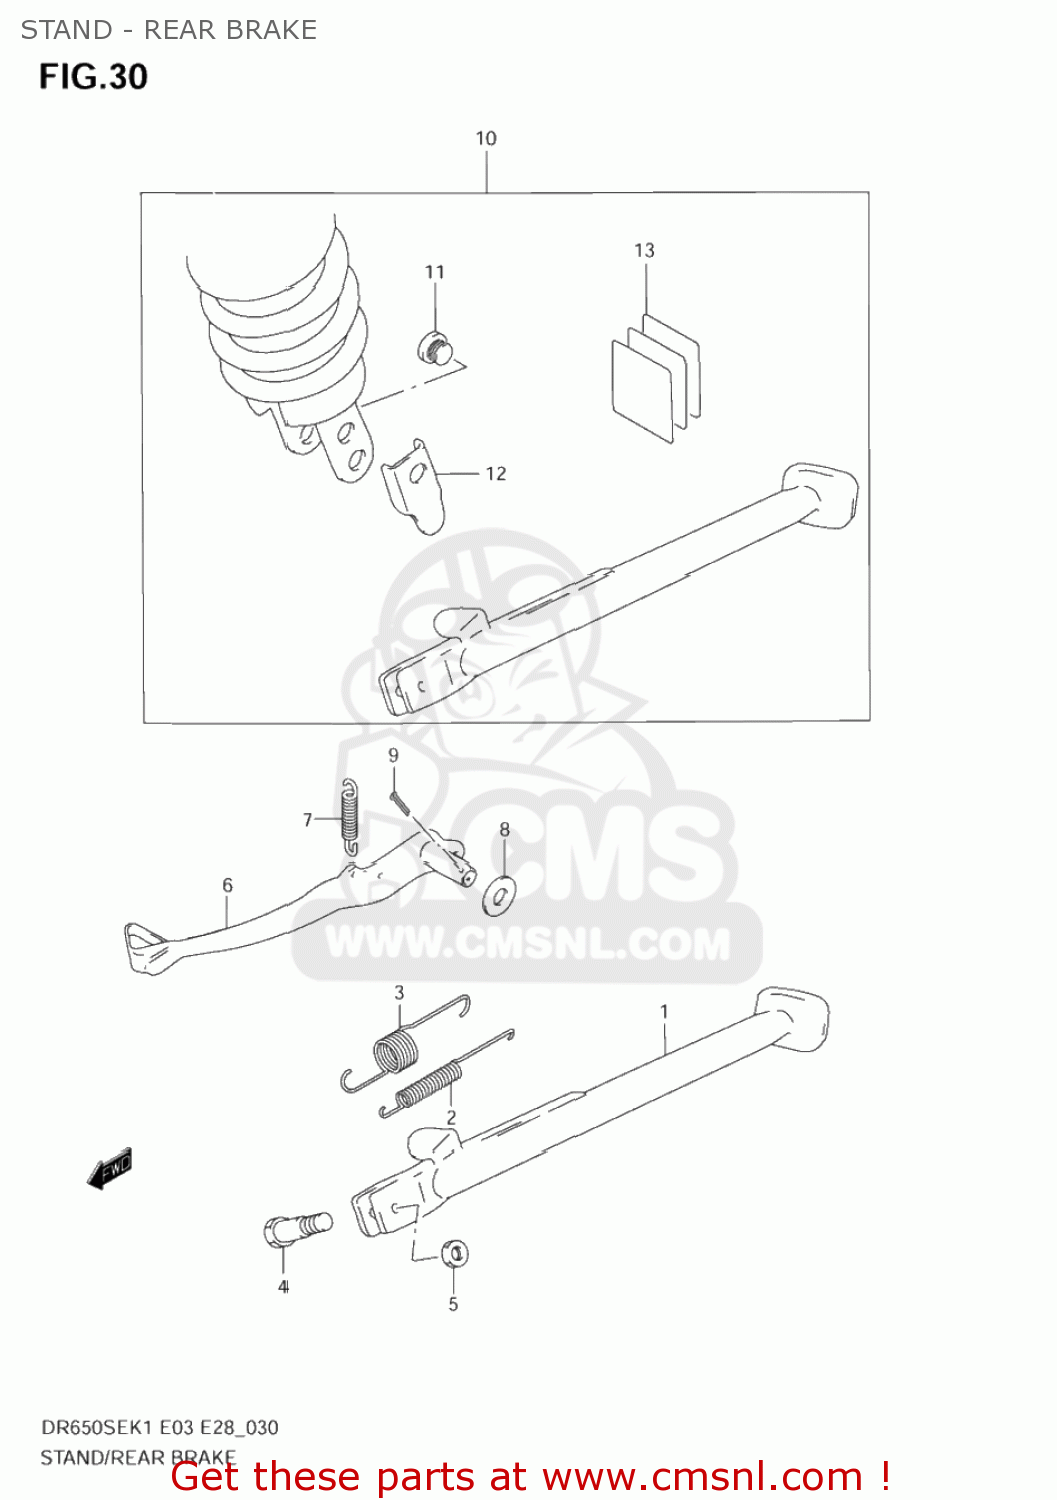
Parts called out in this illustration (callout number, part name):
1	STAND,PROP
2	SPRING
3	SPRING
4	BOLT(10X30)
5	NUT
6	PEDAL,BRAKE
7	SPRING
8	WASHER(15.5X24X2.3)
9	COTTER PIN
10	Low Side Stand
11	PLUG
12	PLATE,RR SHOCK ABSORBER LWR
13	LABEL SET,WARNING
